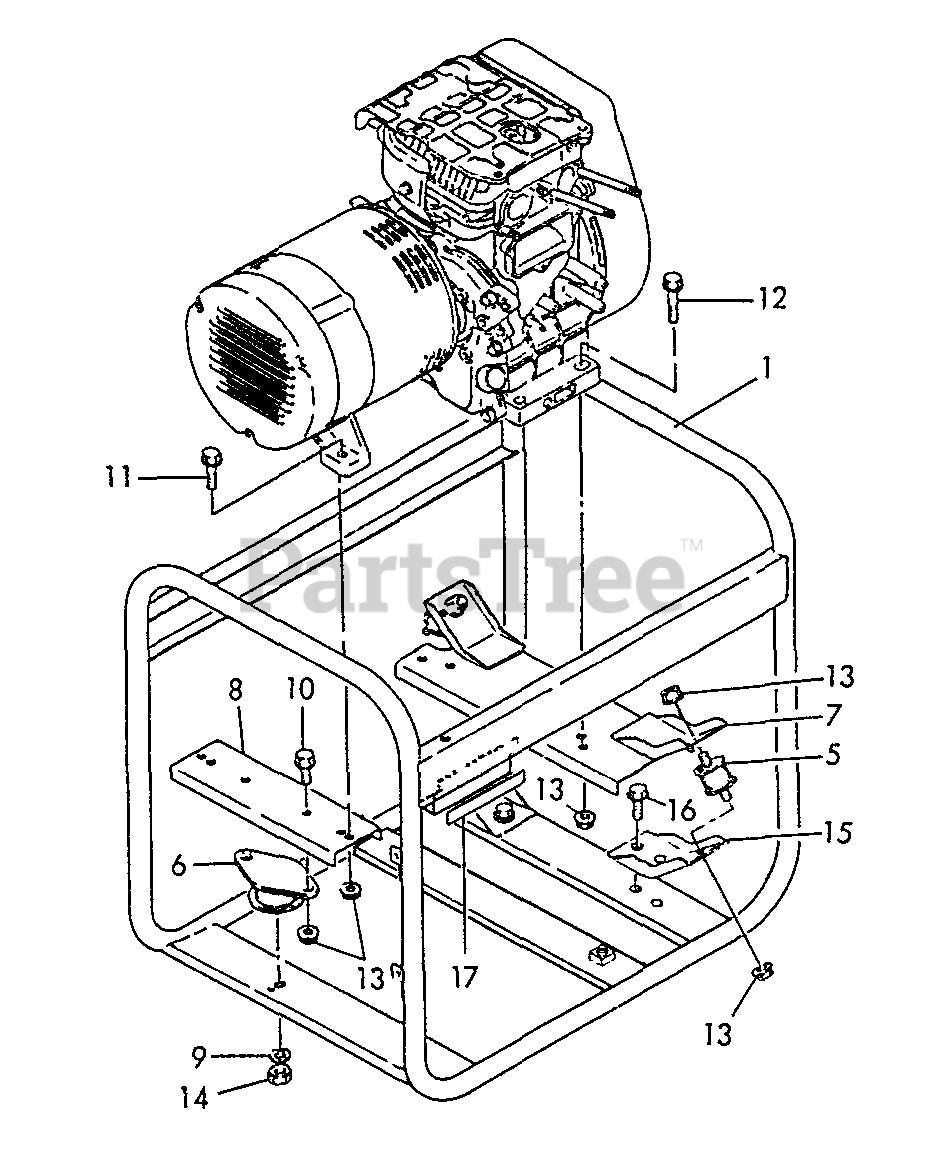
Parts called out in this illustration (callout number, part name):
1	FRAME ASSY
5	DAMPER, FRONT
6	DAMPER, REAR
7	STAY, DAMPER
8	STAY, REAR DAMPER
9	LOCKWASHER - 10
10	BOLT - 8×20 -- PLATED
11	BOLT - 8×30 -- PLATED
12	BOLT - 8×38 -- PLATED
13	U-NUT M8
14	NUT - 10
15	DAMPER STAY, LOWER
16	BOLT - 8×16 -- PLATED
17	SHEET, FRAME
